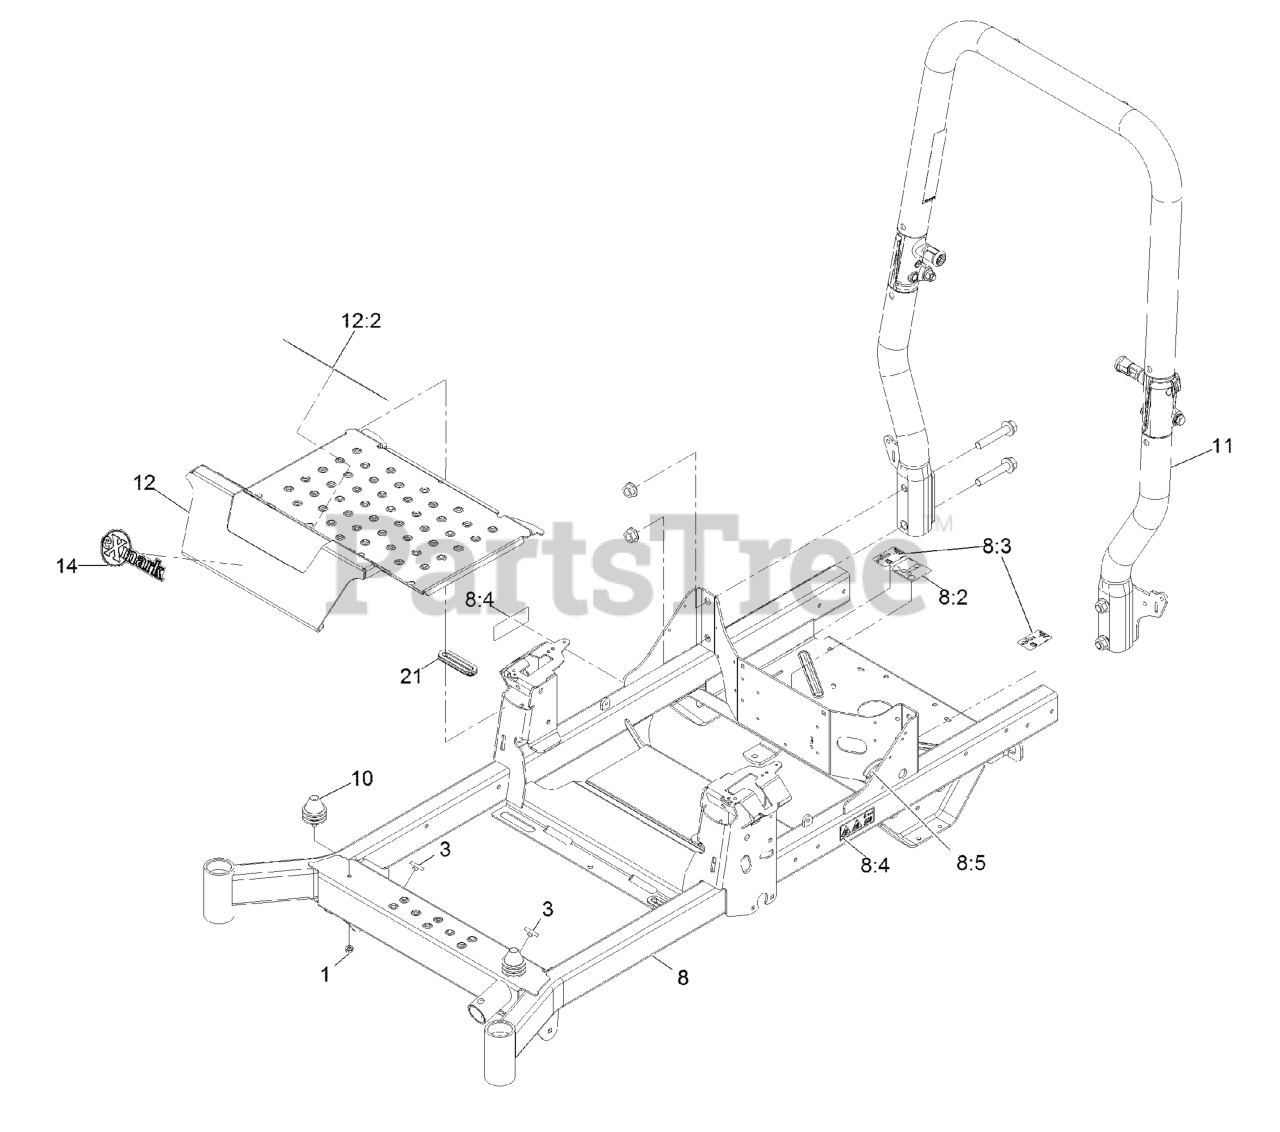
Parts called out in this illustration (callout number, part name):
1	NUT-HF, NI
3	BUMPER-PUSH-IN, RUBBER
8	FRAME ASM
8:2	DECAL-ROUTING, BELT
8:3	DECAL-RELEASE, DRIVE
8:4	DECAL-WARNING
8:5	STRIP-SEAL
10	ISOLATOR
11	ASM-ROPS TAPERED
12	PAN-FLOOR
12:2	DECAL-DANGER
14	DECAL-EXMARK LOGO
21	GROMMET-RUBBER
